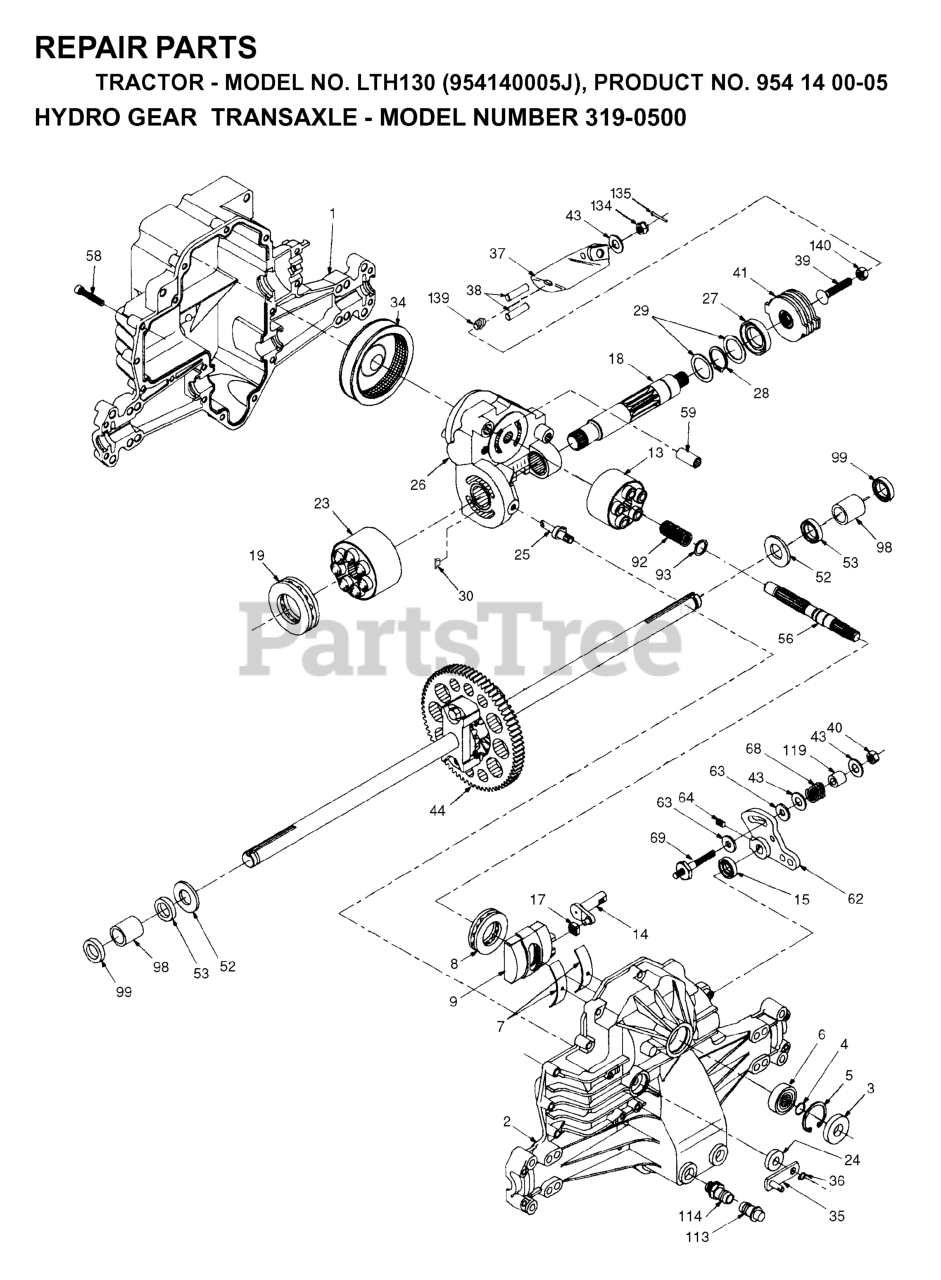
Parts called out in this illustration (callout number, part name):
1	Housing, Lower
2	Assembly, Upper Housing
3	Seal, Lip
8	Bearing, Thrust 30 x 52 x 13
13	Block, Cylinder Assembly
15	Seal, Lip
18	Shaft, Motor
19	Bearing, Thrust 42 x 68 x 16
23	Block, Cylinder Assembly
24	Seal, Lip 10 x 25 x 7
25	Actuator, Bypass
26	Center Section Assembly Kit
27	Seal, Lip 26 x 42 x 8
28	Ring, Retaining
29	Washer 26 x 35 x 1
34	Oil Filter Element
35	Arm, Bypass
36	Ring, Retaining
37	Arm, Actuating
38	Pin, Actuating
39	Bolt 5/16-24 x 1-3/4
40	Nut, Nylon Insert Hex Lock 5/16-24
41	Brake Rotor/Stator Kit
43	Washer 7/8 O.D. x 7/16 x .060
44	Differential Assembly
52	Washer 3/4 x 1.5 x .13
53	Seal .75 x 1.25 x .250
56	Shaft, Input
58	Bolt 1/4-20 x 1.38
59	Pin .5 OD x .43 ID x .750
62	Arm, Control
63	Puck, Dampener
64	Set Screw
68	Spring
69	Stud 5/16-24
92	Spring, helical compression
93	Washer, Block Thrust
98	Sleeve Bearing
99	Seal, Wiper
113	Cap, Vent Assembly
114	Fitting, O-Ring Assembly
119	Spacer
134	Nut, Castle 5/16-24
135	Pin, Cotter
139	Spring, Compression
140	Nut, Hex 5/16-24
